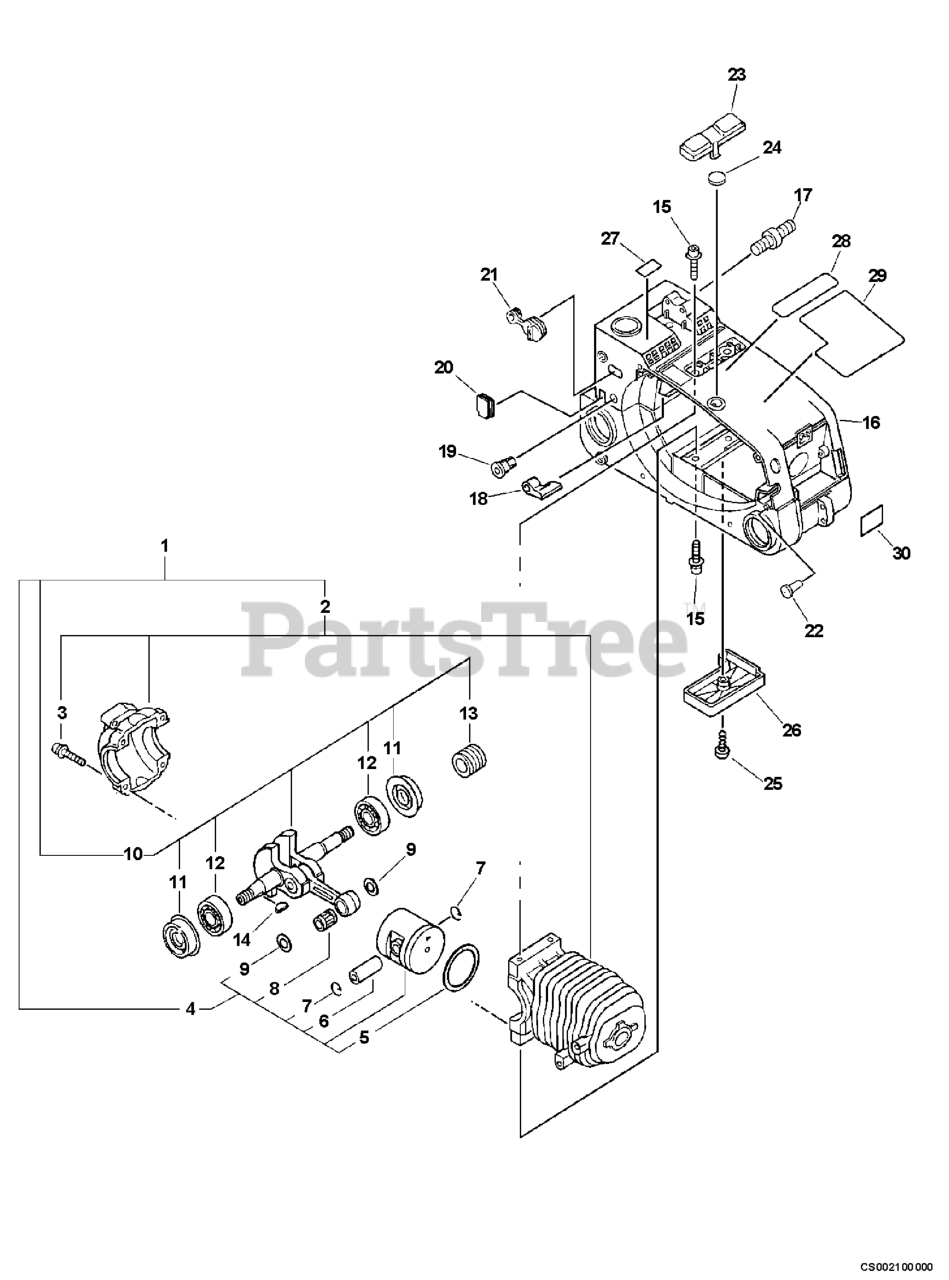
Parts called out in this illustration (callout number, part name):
1	SHORT BLOCK
2	CRANKCASE KIT
3	SCREW 5x25
4	PISTON KIT
5	RING, PISTON
6	PIN, PISTON
7	RING, SNAP
8	BEARING, NEEDLE 8
9	WASHER, THRUST
10	CRANKSHAFT ASSY
11	SEAL, OIL
12	BEARING, BALL 6201
13	GEAR, WORM
14	KEY, WOODRUFF
15	BOLT 5x16
16	COVER, ENGINE - GRAY
17	BOLT, STUD 6
19	GROMMET, IDLE
21	GROMMET, CHOKE
22	VENT ASSY
25	SCREW 4x16
27	LABEL - PURGE PUMP
28	LABEL - CAUTION
30	LABEL - CAUTION - HOT
